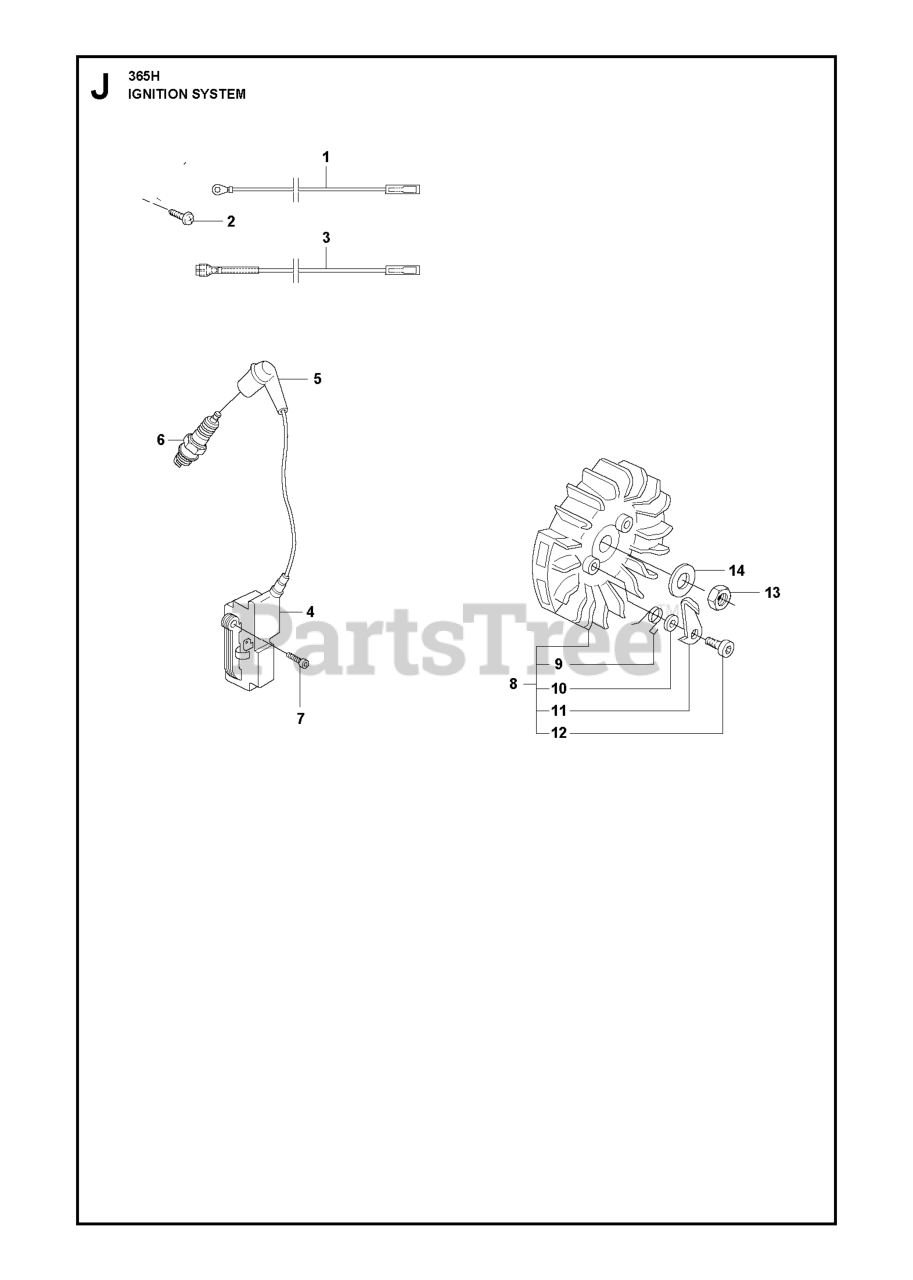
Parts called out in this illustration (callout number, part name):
2	SCREW CITXPANT
4	IGNITION MODULE
5	SPARK PLUG CONN. KIT
6	SPARK PLUG M14X1.25 NGK BPMR7A
7	SCREW ITXSCM M5X20 T27 12.9 T
12	SCREW
14	WASHER 8.4X16
